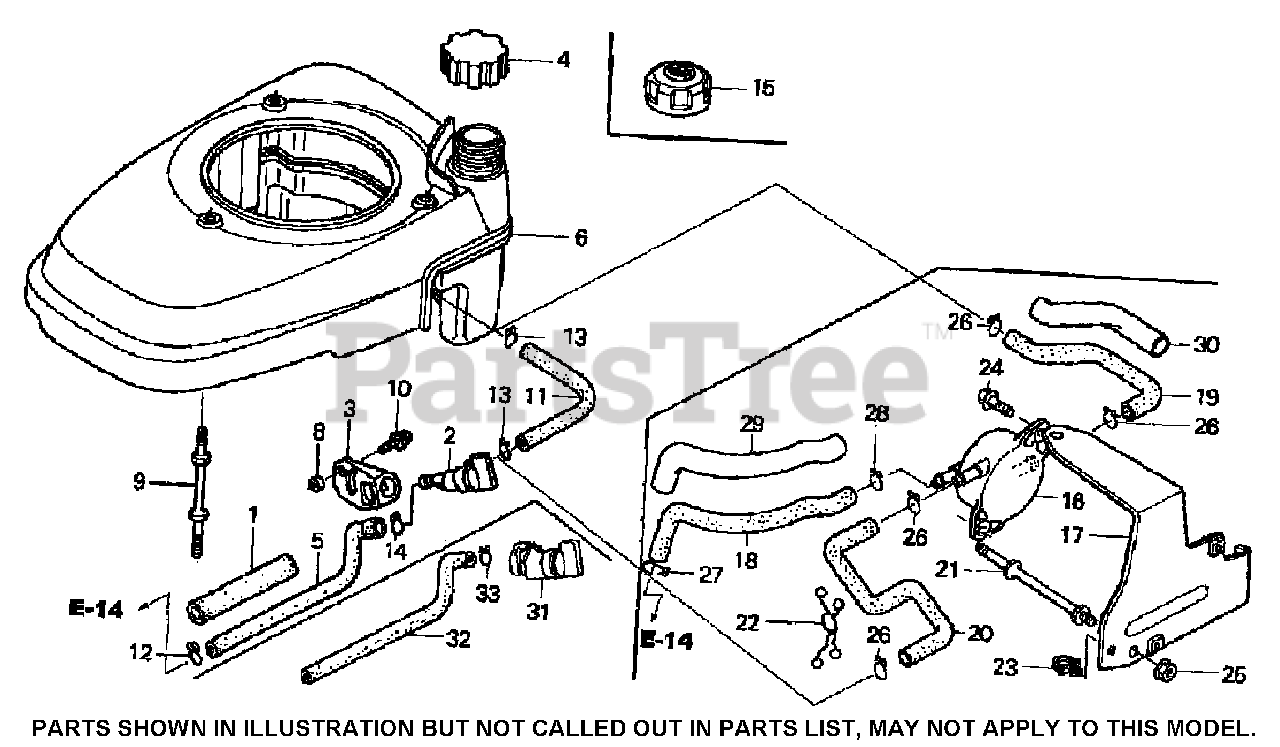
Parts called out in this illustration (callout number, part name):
1	SUPPORTER-RUBBER (107MM)
2	PETCOCK ASM.
3	BRACKET, PETCOCK
4	FUEL TANK CAP ASM
5	TUBE, FUEL
6	COVER-FAN
8	COLLAR-FUEL PETCOCK
9	BOLT-STUD
10	SCREW-WASHER (5X10)
11	TUBE, FUEL TANK
12	CLIP-TUBE (B8)
13	CLIP-TUBE (B10)
14	CLIP-TUBE (C9)
